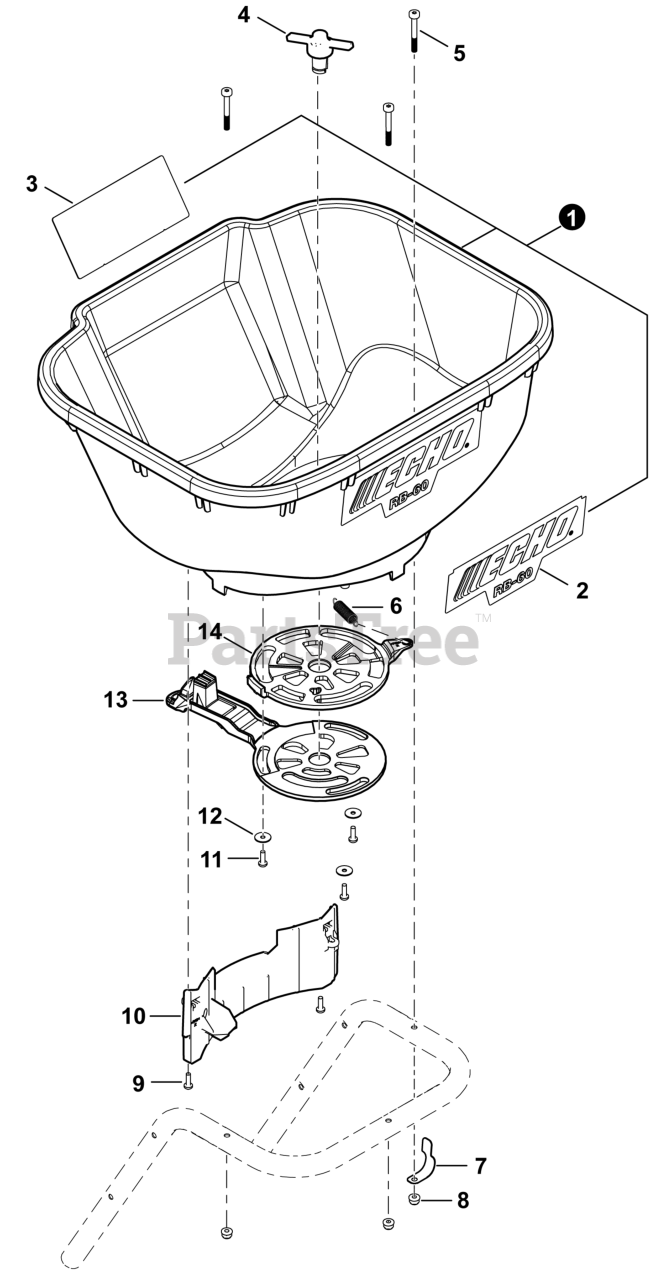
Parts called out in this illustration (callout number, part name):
1	HOPPER
2	LABEL - ECHO
3	LABEL - OPERATION
4	AGITATOR
5	BOLT, M6
8	NUT, FLANGE M6
9	BOLT, TORX 5×16
10	COVER, BRACKET
11	BOLT, TORX 5×20
13	METERING PLATE , LOWER
14	METERING PLATE , UPPER
